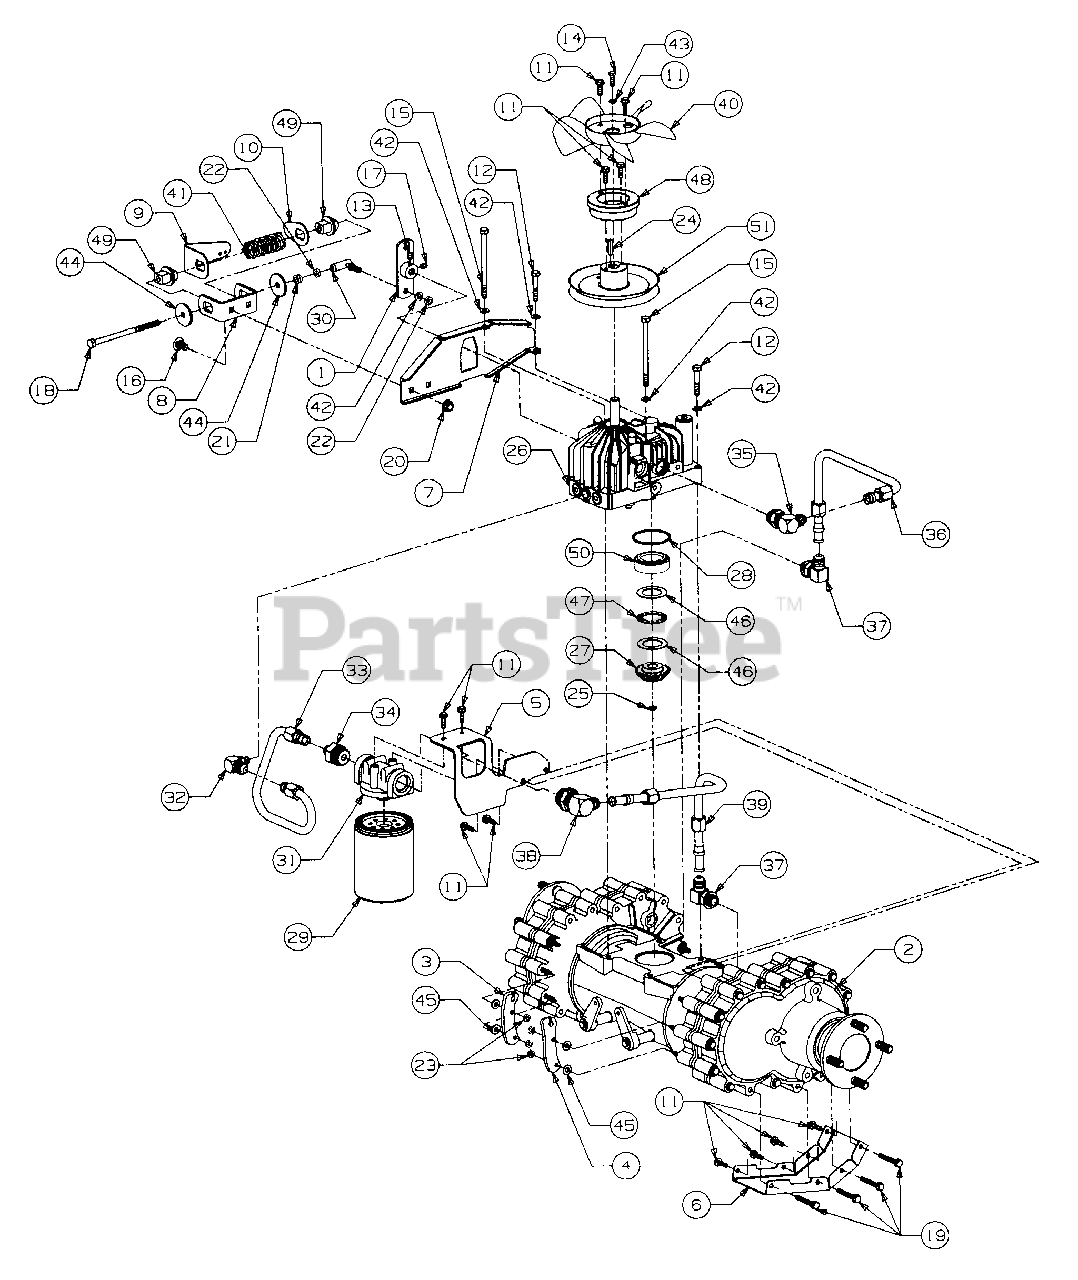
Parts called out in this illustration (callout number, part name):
1	Lever, Forward & Reverse
2	Transmission Assy, Complete
3	Plate, Left Cable Mtg
4	Plate, Right Cable Mtg
5	Bracket, Oil Filter Mtg
6	Plate, Skid
7	Plate, Neutral Mechanism Mtg
8	Bracket, Neutral Mechanism
9	Mount, Switch
10	Stop, Switch
11	Screw, Hex Wash Hd Tapp, 1/4-20 X .75 Lg
12	Screw, Hex Cap, 5/16-18 X 1.75 Lg GR5
13	Set Screw w/Patch
14	Screw, Hex Cap, M6-1.0 X 20 mm Lg GR10.9
15	Screw, Hex Cap, 5/16-18 X 4.5 Lg GR5
16	Bolt Sht Nk Carriage, 3/8-16 X .75 Lg GR5
17	Set Screw w/Patch, 5/16-24 X .38 Lg
18	Screw, Hex Cap, 5/16-24 X 5.37 Lg GR5
19	Screw, Hex Wash Hd Tapp, 1/4-20 X 2.31 Lg
20	Nut, Hex Flanged Lock, 3/8-16 2
21	Nut, Hex, 5/16-24
22	Nut, Hex Jam, 5/16-24 GR5
23	Nut, Hex Top Lock, 1/4-20
24	Key, Square, 5 mm X 5 mm X 25 mm Lg
25	Ring, Snap, .500 Dia Shaft
26	Pump, Hydrostatic
27	Gear, Input Pinion -20T
28	O-Ring, 2.237 ID X.103 Thk
29	Filter, Oil
30	Ball Joint
31	Head, Filter
32	Elbow, 90 Deg w/O-Ring
33	Tube, Hydro Inlet
34	Connector, Straight w/O-Ring
35	Elbow, 90 Deg w/O-Ring
36	Tube, Return
37	Elbow, 90 Deg w/O-Ring
38	Elbow, 90 Deg w/O-Ring
39	Tube, Filter Inlet
40	Fan, Hydro 8"
41	Spring, Compression, 1.20 OD X 2.70 Lg
42	Washer, Lock, 5/16
43	Washer, Lock, 1/4
44	Washer, Flat, .206 X .448 X .105 Thk
45	Washer, Flat, .25 X .62 X .0515 Thk
46	Washer, Thrust, 1.25X 1.937 X .031 Thk
47	Bearing, Thrust, 1.25 X 1.937 .0781 Thk
48	Hub, Fan Mtg
49	Guide, Neutral Stop
50	Spacer, Input Pinion
51	Pulley, Transmission Drive
